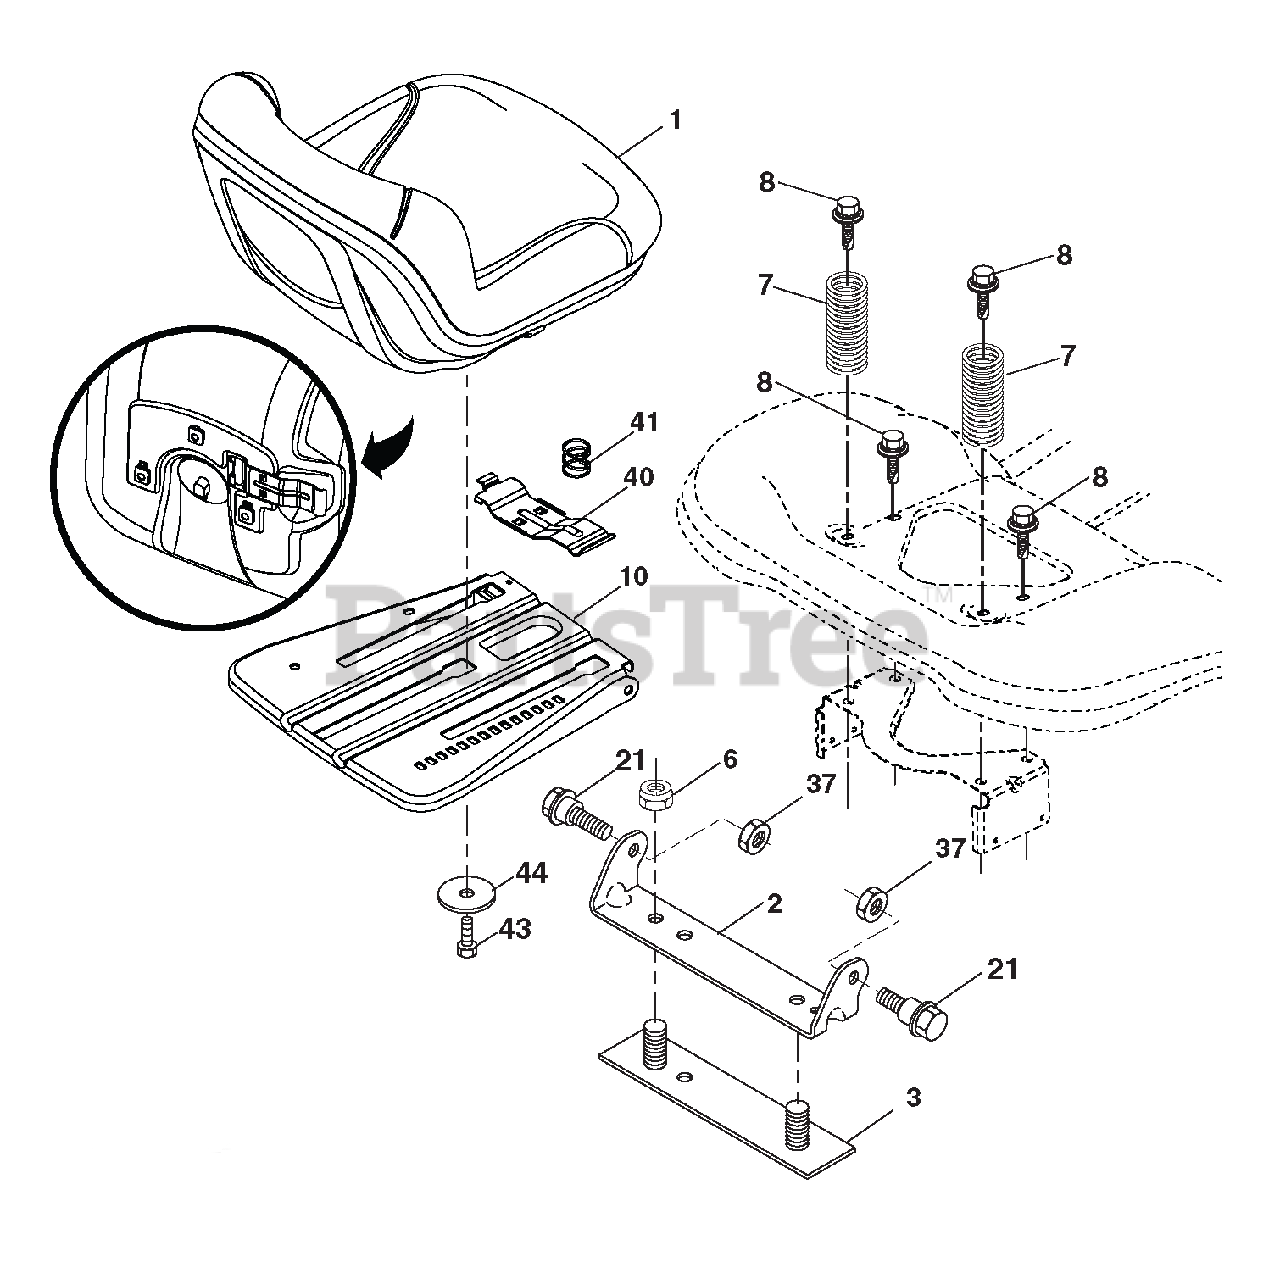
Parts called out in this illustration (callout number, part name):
1	SEAT.TA150.KB/SLD.BLK.ARIENS
2	BRACKET.PIVOT.FENDER.2002
3	STRAP ASM.FENDER.94
6	Locknut, Washer Insert 3/8-16
7	SPRING.SEAT.CPRSN.2.250.BLK.ZI
8	BOLT.5/16-18UNCX3/4 W/SEMS.BLK
10	PAN ASM.SEAT.3PT.
21	BOLT.SHLD.5/16-18 UNC-2A.BLK D
37	Locknut, Washer Insert 5/16-18
40	HANDLE.SLIDE.SEAT.TEX.MILSCO
41	SPRING.LATCH.SEAT.TEX
43	BOLT.FIN.HEX.3/8-16UNC X 3/4
44	WASHER.13/32 X 2 3/8 X 12GA.
